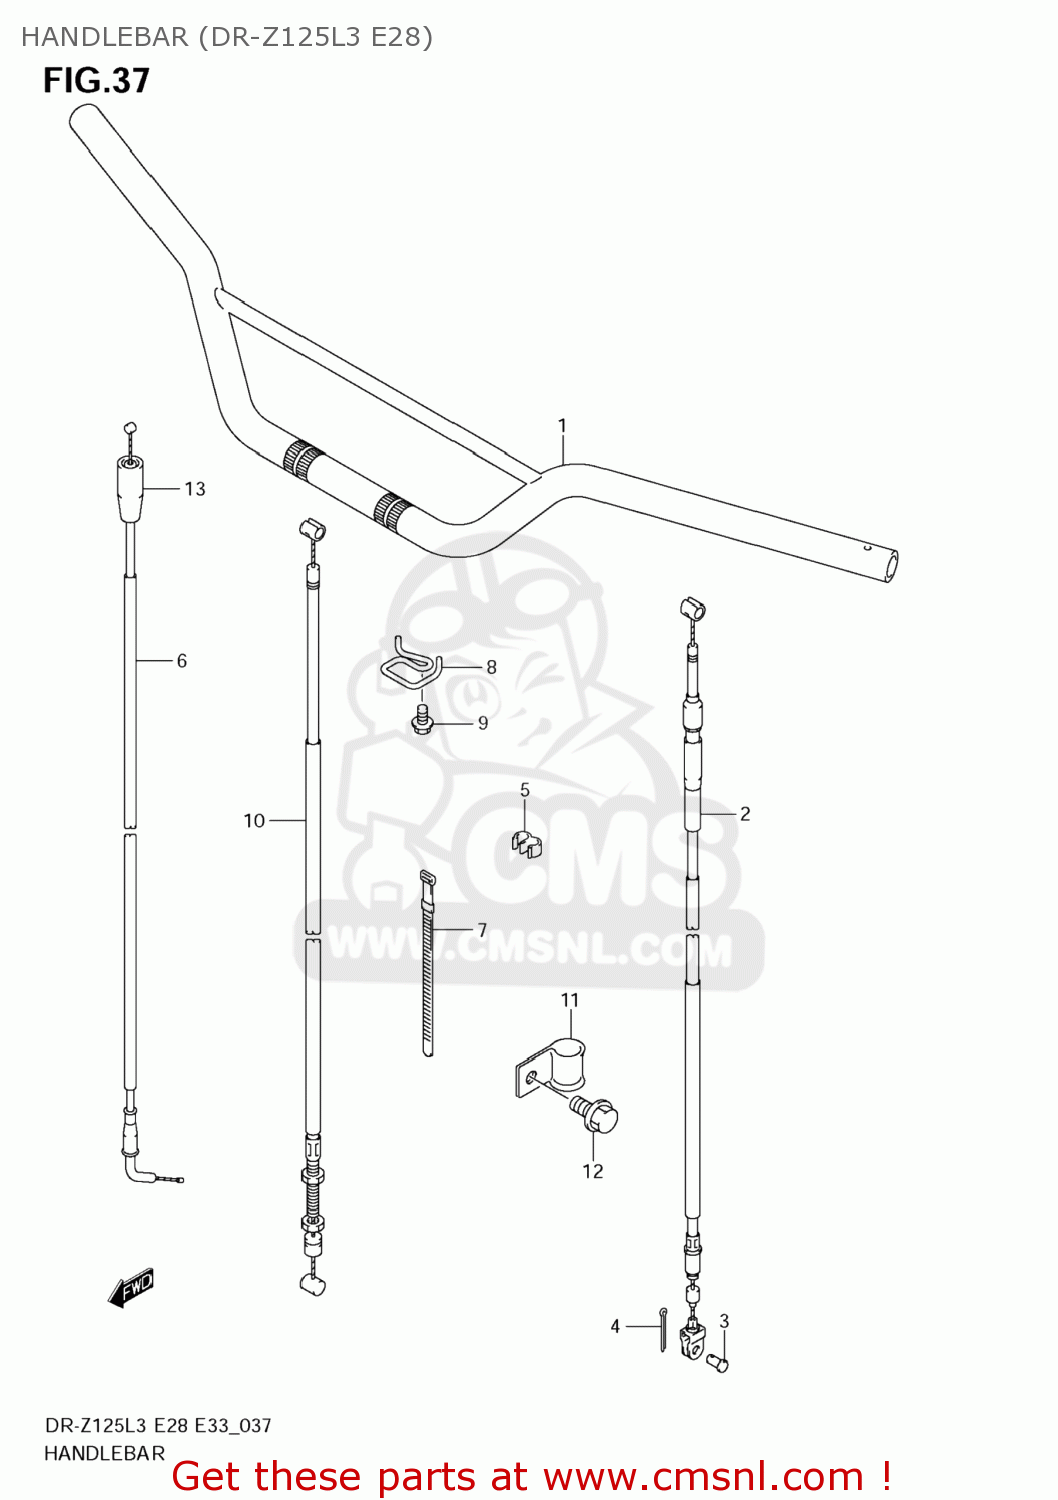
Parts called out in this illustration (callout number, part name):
1	HANDLEBAR(SILVER)
2	CABLE ASSY,CLUTCH
3	PIN(L:13)
4	PIN
5	CLAMP
6	CABLE ASSY,THROTTLE
7	CLAMP(L:90)
8	GUIDE,CABLE
9	BOLT
10	CABLE,FR BRAKE
11	CLAMP,FR BRAKE CABLE
12	BOLT
13	COVER,THROTTLE CASE
